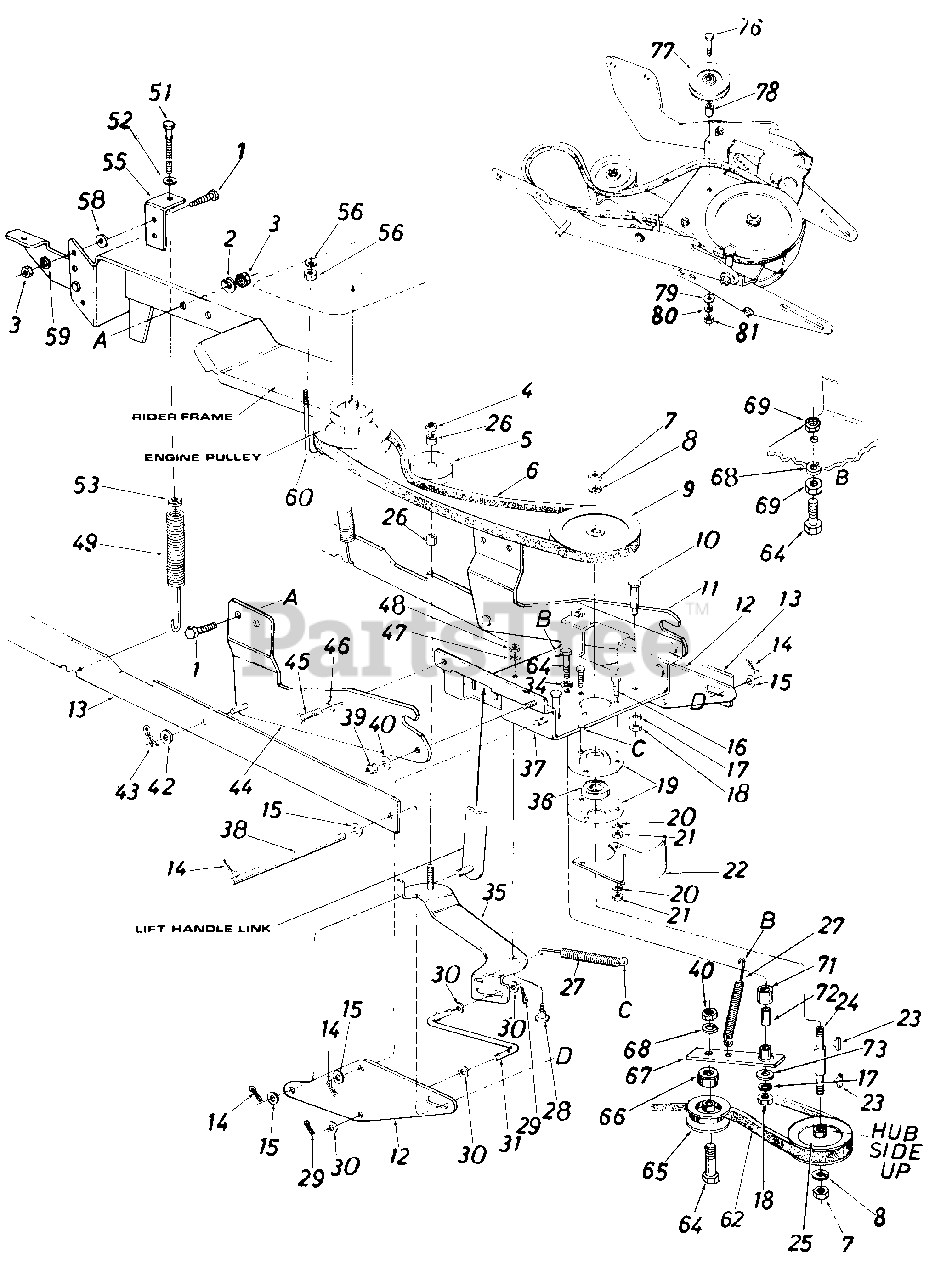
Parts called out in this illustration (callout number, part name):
1	Hex Bolt 1/4-28 x .75" Lg. Grade 5
2	L.-Wash. 1/4" I.D.
3	Hex Nut 1/4-28 Thd.
4	Hex Cent. L-Nut 3/8-16 Thd .
5	Idler Pulley
6	"V"-Belt 1/2 x 49" Lg.
7	Hex Jam Nut 5/8-11 Thd.
8	L-Wash. 5/8 ' I.D.
9	6.50" O.D. x 5/8 Pulley
10	Shoulder Bolt
11	Channel Supporting Brkt.-R.H.
12	Linkage Brkt.
13	Linkage Arm Ass'y.
14	Intern. Cotter Pin .50 Dia.
15	Fl.-Wash.
16	Hex Bolt 5/16 x 1.25" Lg.
17	L.-Wash. 3/8" I.D.
18	Hex Jam Nut 3/8-16 Thd.
19	Bearing Housing
20	L.-Wash. 5/16" I.D.
21	Hex Nut 5/16-18Thd.
24	Pulley Spindle
25	5/8 Pulley-6.28 I.D. x 5.56 O.D.
26	Spacer .383 I.D. x .503 O.D. x .562 Lg.
27	Extension Spring .54 O. D . x 5.25"
28	Shoulder Bolt
29	Cotter Pin 3/32" Dia. x 1.0
30	FI.-Wash.
31	Control Rod
34	Hex Sems Scr. 5/16-18 x 1.0" Lg.
35	Clutch Idler Brkt. Ass'y.
36	Ball Bearing
37	Channel Ass'y.
38	Lift Handle Shaft
39	Hex Jam Nut 3/8-16 Thd.
40	L.-Wash. 3/8" I.D.
42	Fl.-Wash.
43	Intern. Cotter Pin .50" Dia.
44	Channel Supporting Brkt.-L.H.
45	Hex Bolt 3/8-16 x x 1.0" Lg.
46	L.-Wash. 3/8" I.D.
47	L.-Wash. 5/16" I.D.
48	Hex Nut 5/16-18 T hd .
49	Helper Spring
51	Hex Scr. 5/16 18 x 2.0" Lg. Special
52	Bell Wash. .345 I.D. x .88 O.D. x .06
53	Spring Insert
58	Fl.-Wasn. .264' I.D.
59	L.-Wash. 1/4" I.D.
60	J-Bolt 5/16-18 Thd.
62	"V"-Belt 1/2 "A' x .89" Lg.
64	Hex Bolt 3i8-16 x 2.0" Lg.
65	Idler Pulley
66	Spacer .385 I.D. x 503 O.D. x.562" Lg.
67	Idler Arm Ass'y.
68	L.-Wash. 3/8" I.D.
69	Hex Jam Nut 3/8-16 Thd.
71	Hex Bolt 5/16-19 x 1 1/4"
72	Spacer .3775 I.D. x .60 O.D. x8.3 Lg.
73	Fl.-Wash. 3/8 I.D. x 1" O.D.-x 1.27
76	Hex Bolt 3/8 16 x 2.5" Lg. (Grade 5)
77	Idler Pulley .38 I.D. x 3.06 O.D.
78	Spacer .385 I.D. x .630 O.D. x .76 Lg.
79	Fl. Wash. .39 I.D. x 1-3/4 O.D. x 3/1 6"
80	L-Wash. 3/8" I.D.
81	Hex Nut 3/8-16 Thd.
